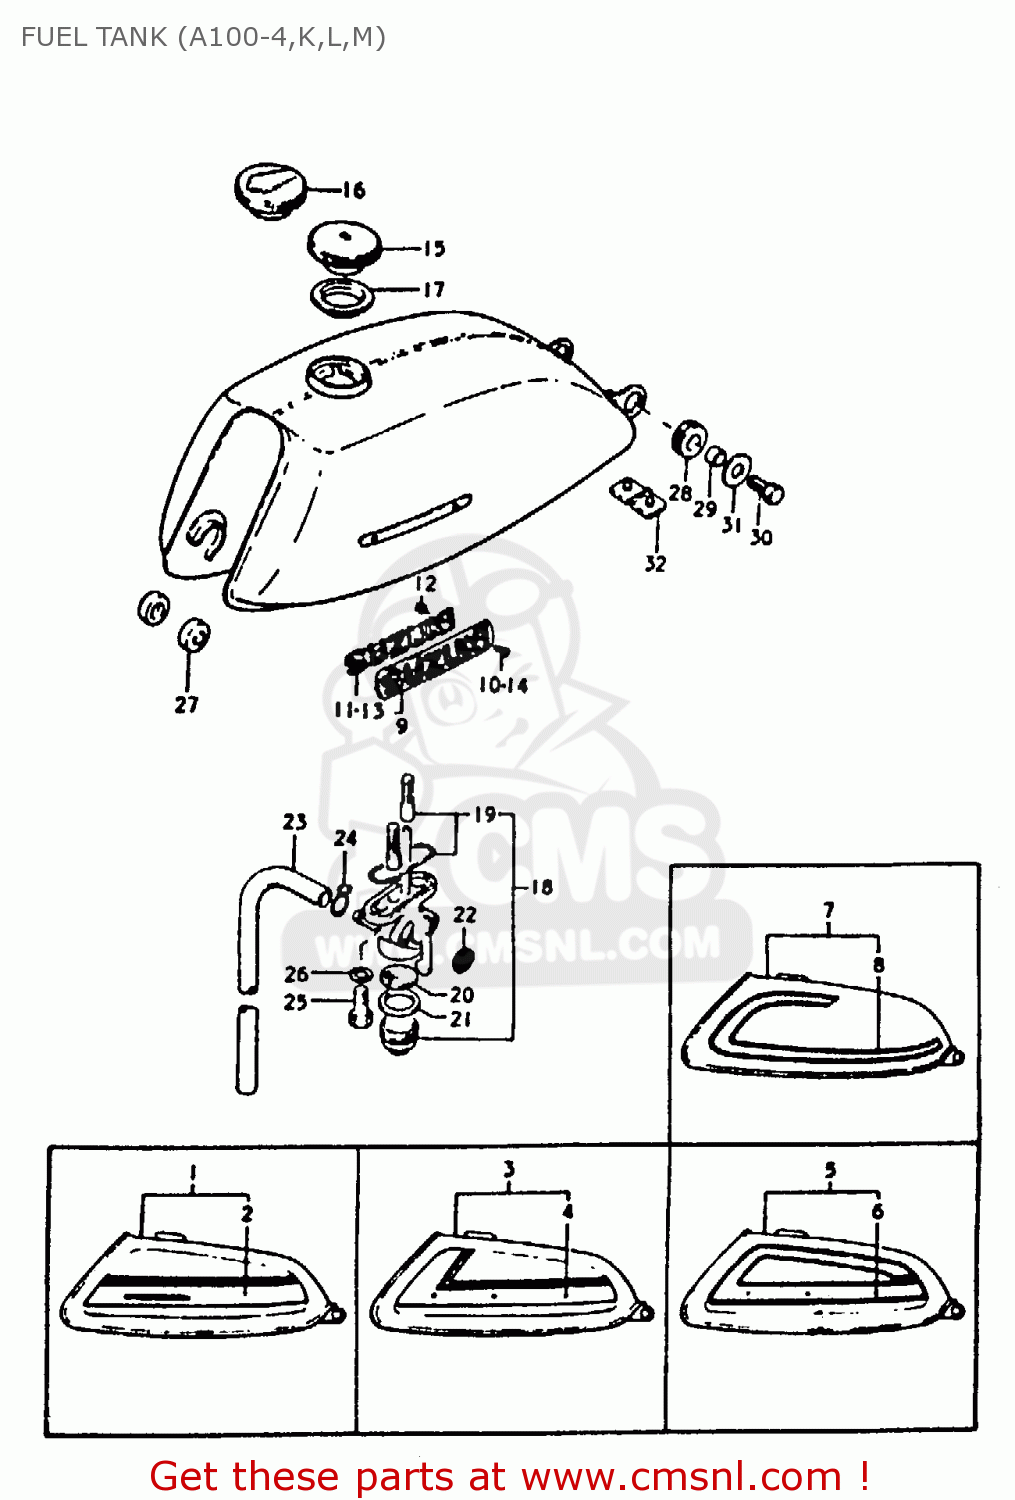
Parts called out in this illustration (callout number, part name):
1	TANK, FUEL
2	TAPE SET
3	TANK, FUEL
4	TAPE SET
9	EMBLEM
10	SCREW
11	EMBLEM
12	NUT
15	CAP SET,FUEL TANK
17	GASKET,FUEL TANK CAP (NAS)
18	COCK ASSEMBLY,FUEL
19	COCK ASSEMBLY,FUEL
20	NET,STRAINER
21	GASKET,FILTER (NAS)
22	GASKET,LEVER (NAS)
23	HOSE
24	CLIP
25	BOLT(6X20)
26	GASKET
27	CUSHION
28	CUSHION
29	SPACER
30	BOLT, UPPER
31	WASHER (6.5X24X1.6)
32	CUSHION
